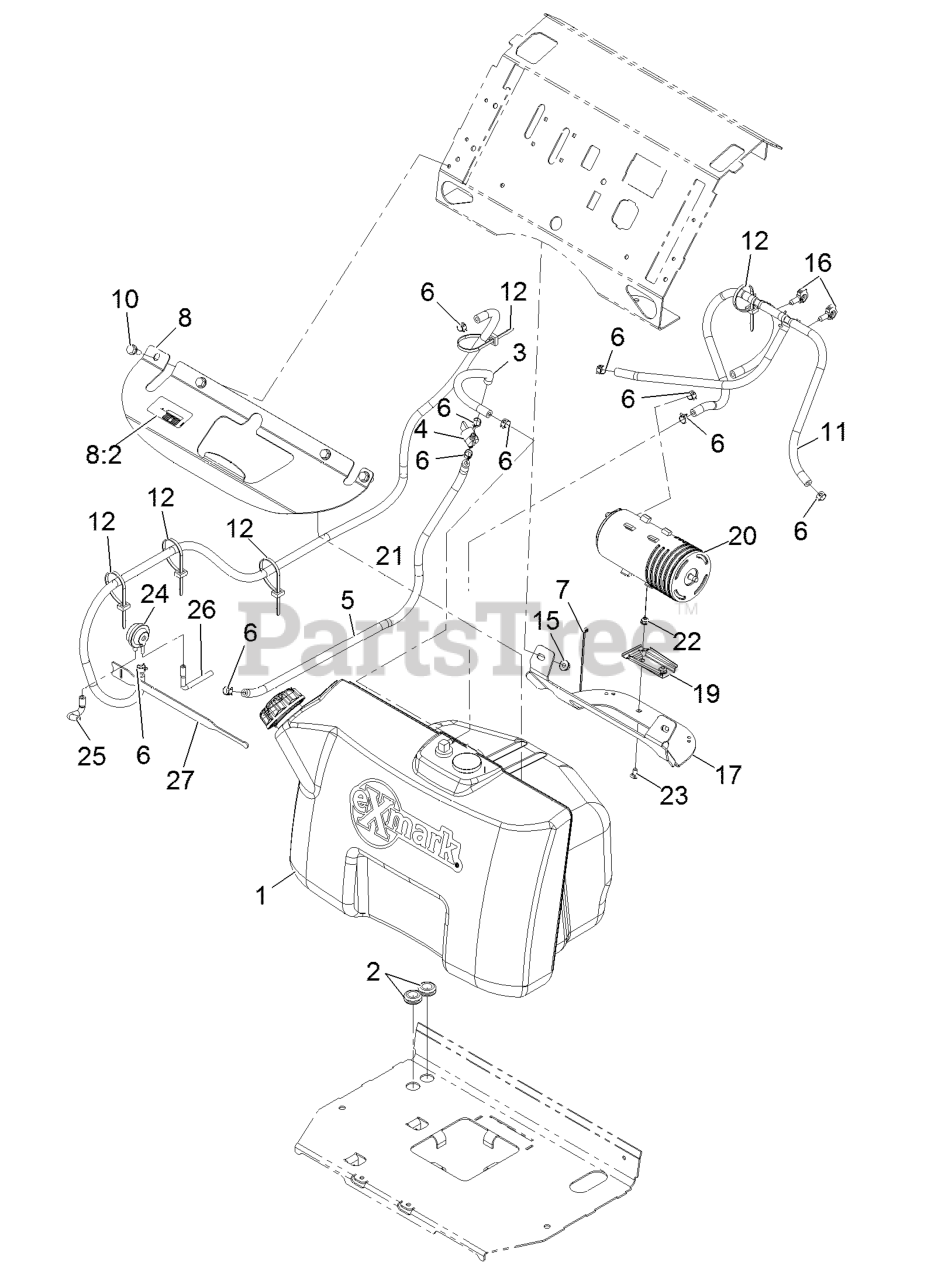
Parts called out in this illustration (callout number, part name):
2	GROMMET
3	HOSE-FUEL
4	VALVE-FUEL
5	HOSE-FUEL
6	CLAMP-HOSE
7	TIE-CABLE
8	BRACKET-TANK
8:2	DECAL-FILL, FUEL
10	SCREW-THD ROLL, HWH
11	VENT ASM
12	TIE-CABLE
15	NUT-HF, NI
16	CLIP-HARNESS
17	BRACKET,CARB CANISTER
19	BRACKET-CANISTER, CARBON
20	CANISTER-CARBON, 800CC
21	HOSE-FUEL .25 X 60.00, J3
23	SCREW-CARR
24	VALVE-CONTROL, VACUUM
25	HOSE-VENT, FORMED
26	HOSE-VENT, FORMED
27	STRAP-VELCRO, CABLE TIE
